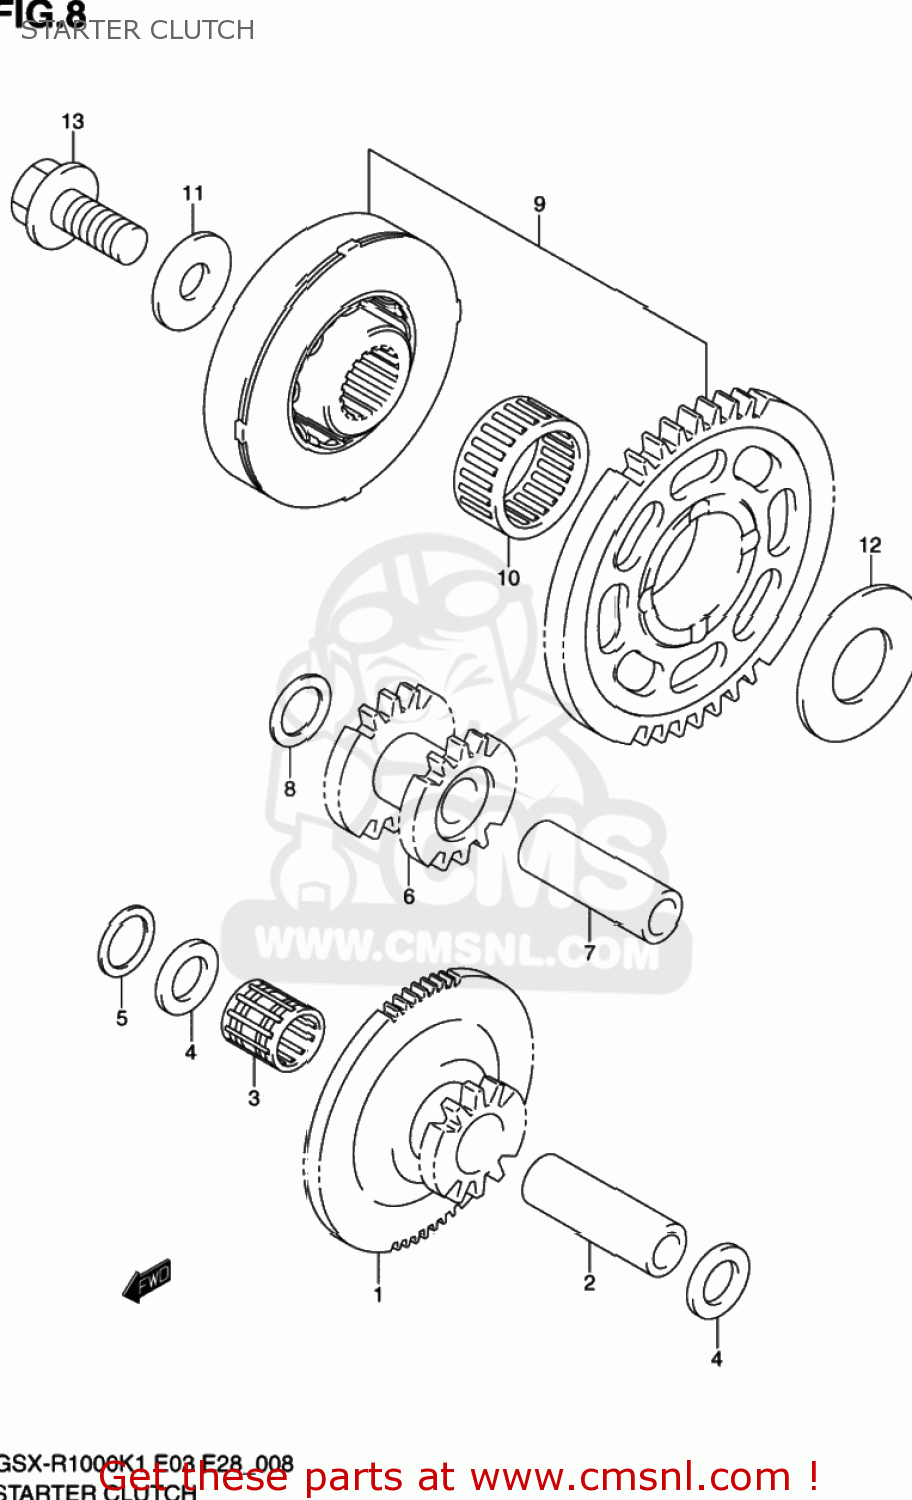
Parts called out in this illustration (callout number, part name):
1	GEAR,STARTER IDLE NO.1
2	PIN,PISTON
3	BEARING(12X16X16)
4	SHIM(12X20X1)
5	WASHER
6	GEAR,STARTER IDLE NO.2
7	PIN,PISTON
8	WASHER
9	CLUTCH SET,STARTER
10	BEARING
11	WASHER
12	WASHER
13	BOLT(10X23)
